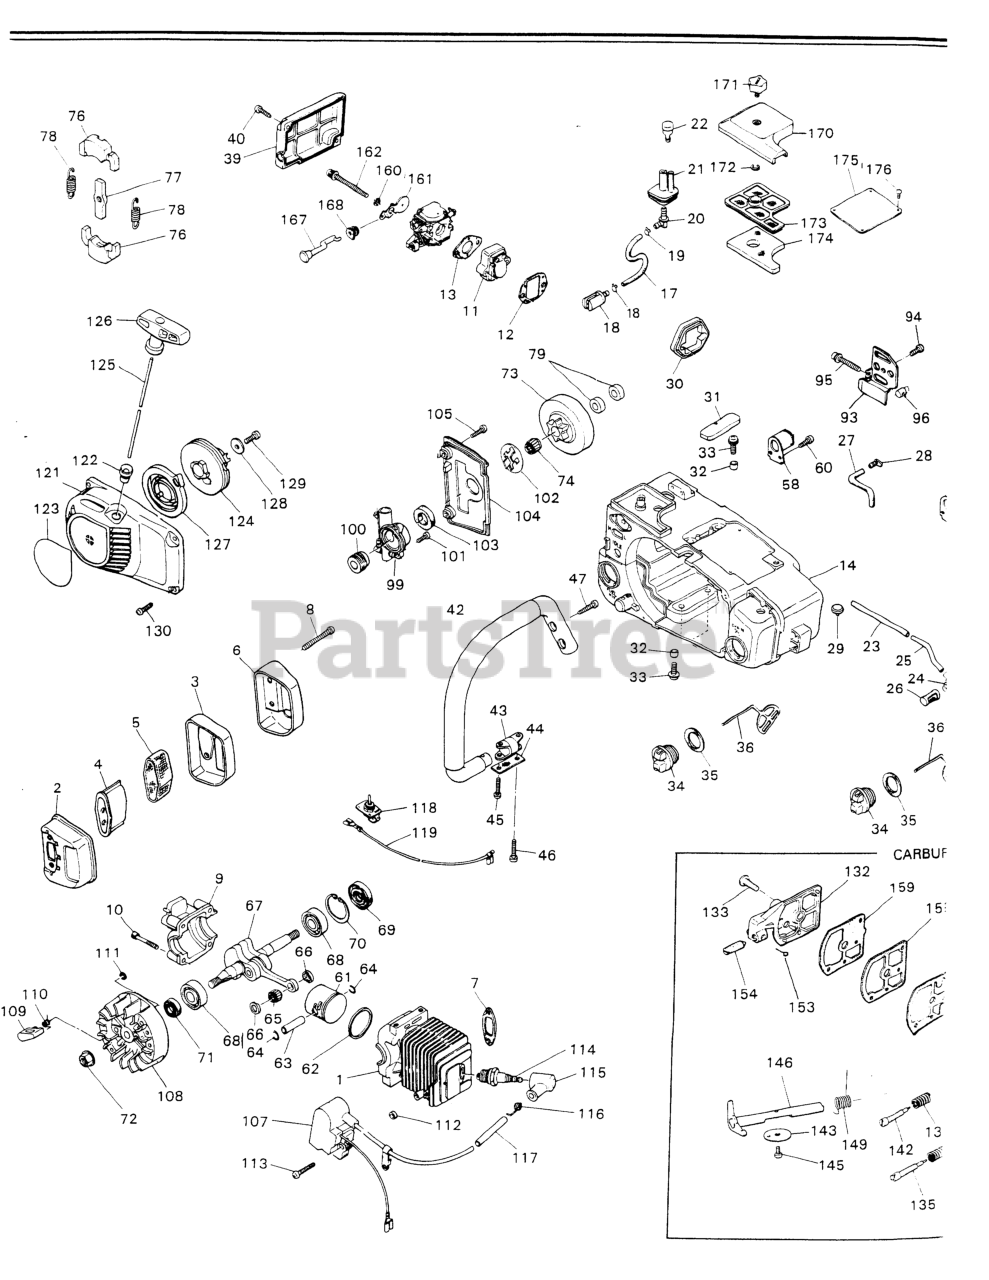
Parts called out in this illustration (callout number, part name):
3	COVER
4	BAFFLE
5	ARRESTER
7	GASKET
10	BOLT, M5 X 30
13	GASKET, CARB (USE -14121)
17	PIPE (USE -85411)
19	CLIP (REPLACES 2841-31280)
21	GROMMET
22	BREATHER ASSY (RPLS 2630-31270
23	PIPE (USE -85411)
24	GROMMET (RPLS -31320)
27	PIPE (USE -85411)
28	PIN
29	VALVE A
35	GASKET
40	SCREW
42	HANDLE (NLA)
44	STOPPER (RPLS -32150)
60	SCREW (REPLACES 50030272)
64	RING, SNAP (RPLS 1101-41320)
65	BEARING
66	WASHER, THRUST (NLA)
67	SHAFT COMP
69	SEAL, OIL
70	RING, SNAP, M32 x 1.2
74	BEARING
76	SHOE, CLUTCH
78	SPRING
79	WASHER, THRU (B)
94	SCREW
96	NUT
100	GEAR
102	PLATE
103	SEAL
105	SCREW
113	SCREW, M4x25 (RPLS.0260-30425)
116	SPRING
117	TUBE
118	SWITCH A
122	GUIDE (RPLS -75120)
123	LABEL, MODEL
127	HOLDER COMPLETE
130	SCREW
132	COVER (NLA)
145	SCREW (NLA)
146	SHAFT A (NLA)
153	PIECE (NLA)
159	KIT, DIAPHRAGM
168	GROMMET
172	RING, SNAP, M4
174	ELEMENT
175	LABEL, WARNING
NI	MUFFLER ASSEMBLY
NI	PIPE COMP (USE -31202)
NI	PIPE ASSEMBLY
NI	HANDLE (F)
NI	CLUTCH ASSEMBLY
NI	KIT, GASKET
NI	ICING KIT
